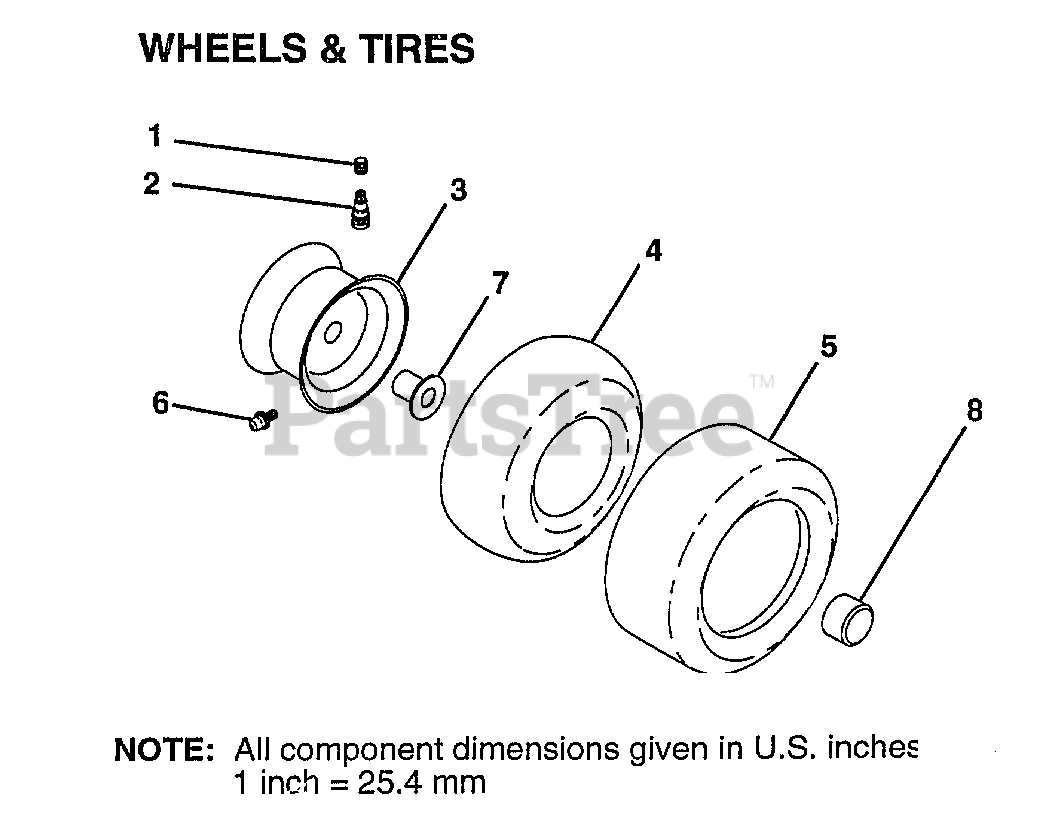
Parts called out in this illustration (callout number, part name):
1	VALVE CAP
2	VALVE STEM LT
3	RIM.FRONT.
3	"WHEEL,REAR"
4	TUBE.16X6.5/7.5-8
4	TUBE.23X8/10-12
6	ZERK FITTING M
7	"FLANGE, BEARING"
8	HUB CAP
